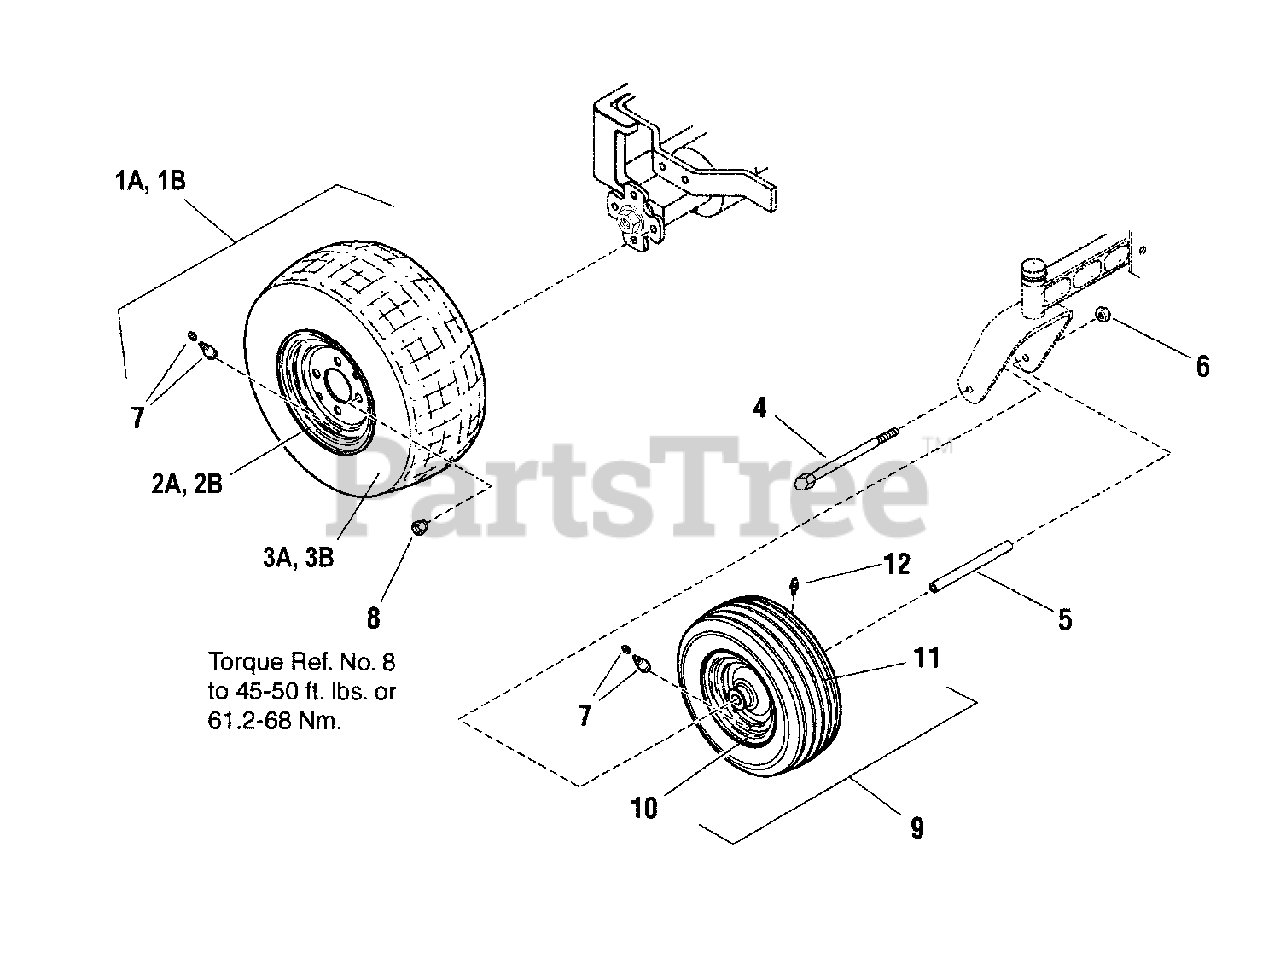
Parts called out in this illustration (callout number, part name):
1A	ASSY, Wheel & Tire, 18 x 6.50-8 K358 (incl. 2A & 3A)
1B	ASSY, Wheel & Tire, 18 x 8.50-8 "Superturf" (incl. 2B & 3B)
2A	RIM, 8 x 6.50, 4 Hole
2B	RIM, 18 x 8.50-8, 4 Hole
3A	TIRE, 18 x 6.50-8 K358
3B	TIRE, 18 x 8.50 4 Ply "Superturf"
4	SCREW, 7/16-14 x 6" Hex Head Cap, GR5
5	TUBE, Caster
6	NUT, 7/16-14 Hex Center Lock
7	AIR VALVE STEM (w/cap)
8	NUT, 1/2-20 for Wheel Bolt- Silver
9	ASSY, Wheel & Tire 11 x 4-5 (Caster)
10	RIM w/Bushings
11	TIRE, 11 x 4-5
12	LUBE FITTING, Angled, M8 x 1
